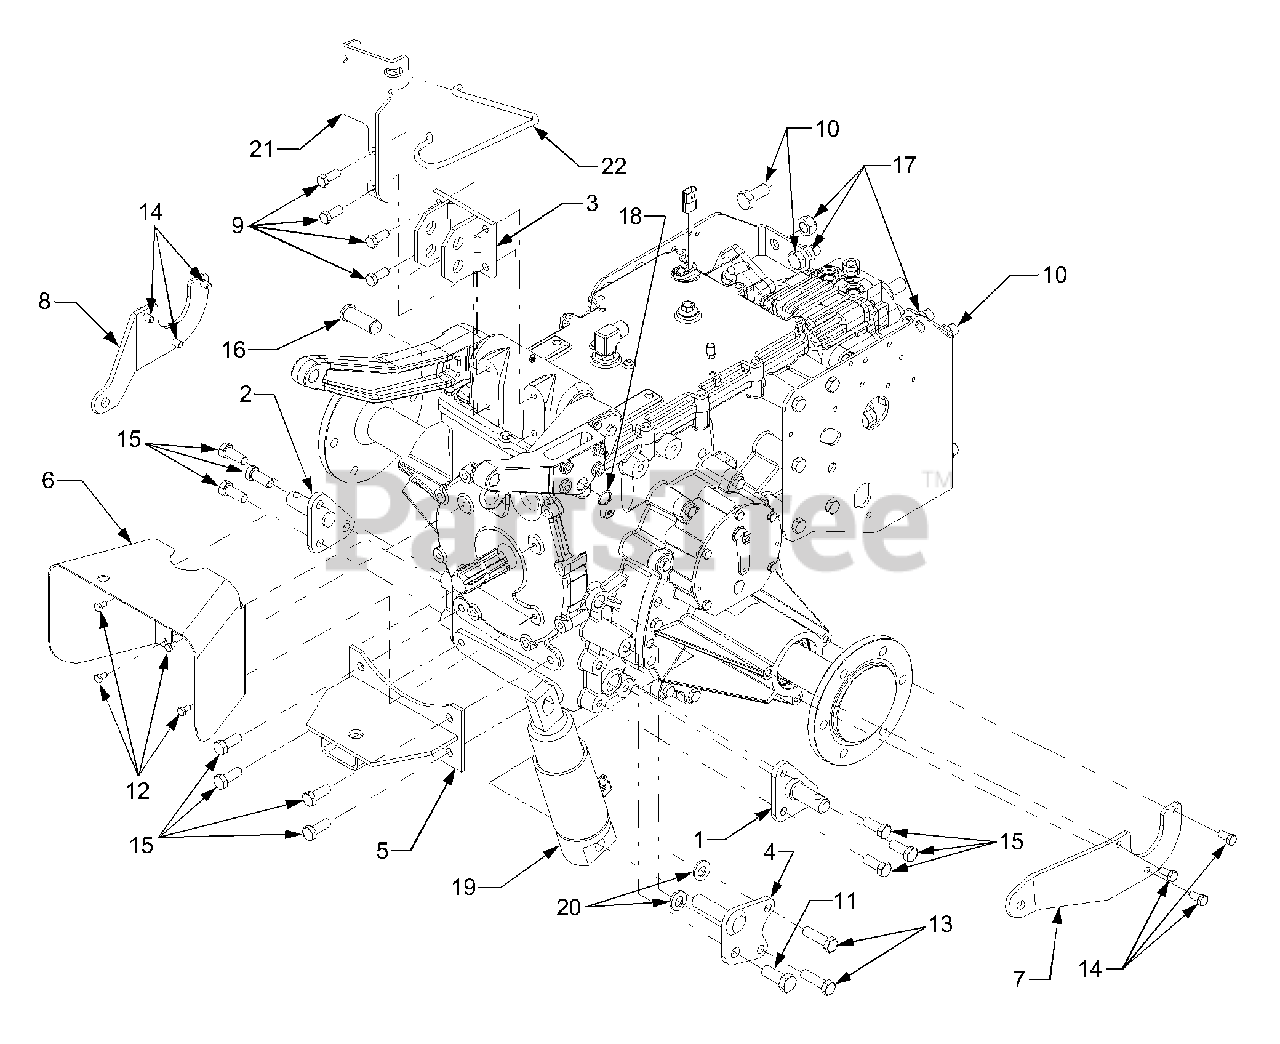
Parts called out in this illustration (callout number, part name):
1	Bracket, Lower Hitch RH
2	Bracket, Lower Hitch LH
3	Bracket, Top Link
4	Bracket, Cylinder
5	Bracket, Drawbar
6	Shield, PTO
7	Bracket, Chain LH
8	Bracket, Chain RH
9	Screw, Hex Cap 7/16-14 x 1/0 GR5
10	Screw, Hex Cap 5/8-18 x 1.31 GR5
11	Screw, Hex Cap 5/8-11 x 1.5 GR5
12	Screw, Hex Cap 5/16-18 x .5 GR5
13	Screw, Hex Cap 1/2-13 x 1.75 GR5
14	Screw, Hex Cap 3/8-16 x .75 GR5
15	Screw, Hex Cap 1/2-13 x 1.0 GR5
16	Pin, Lift, .75 x 2.125
17	Nut, Hex Lock, 5/8-18
18	Ring, Snap, 75 Dia
19	Cylinder, Lift
20	Washer, Flat, .531 x .93 x .09
21	Bracket, Hitch Clip
22	Rod, Top Link Retainer
